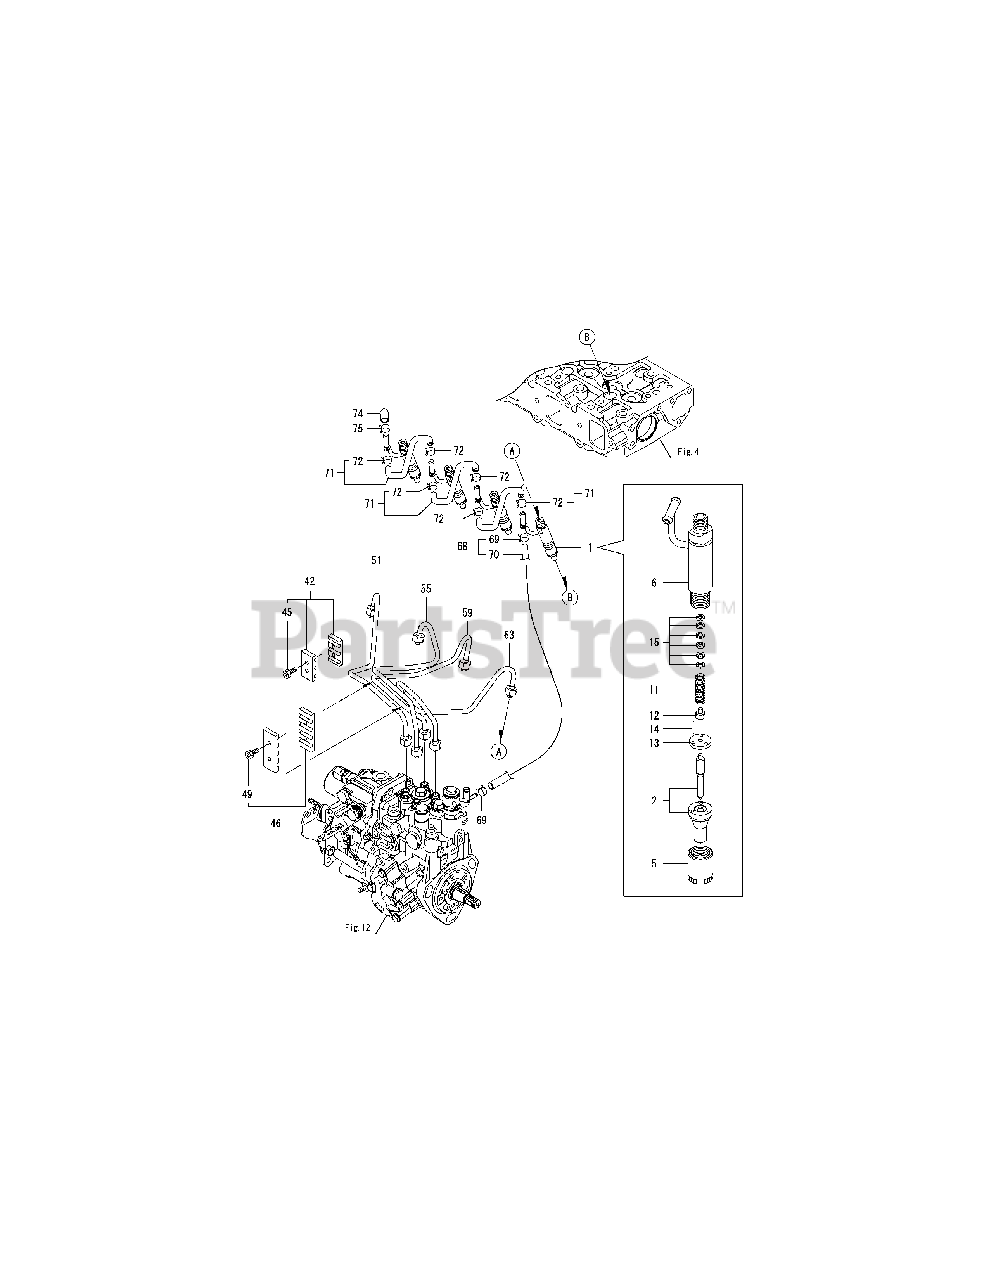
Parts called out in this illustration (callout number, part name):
1	VALVE ASSY, INJECTION ASM
2	VALVE ASSY, INJECTION
6	HOLDER ASSY, NOZZLE
11	SPRING, NOZZLE
15	SHIM SET
42	RETAINER, PIPE
45	BOLT M4X14,HEX.SCKT.
46	RETAINER, PIPE
49	BOLT M4X14,HEX.SCKT.
51	PIPE ASSY, INJECTION
55	PIPE ASSY, INJECTION
59	PIPE ASSY, INJECTION
63	PIPE ASSY, INJECTION
68	PIPE ASSY, RETURN
70	PIPE, FUEL RETURN
71	PIPE ASSY, RETURN
